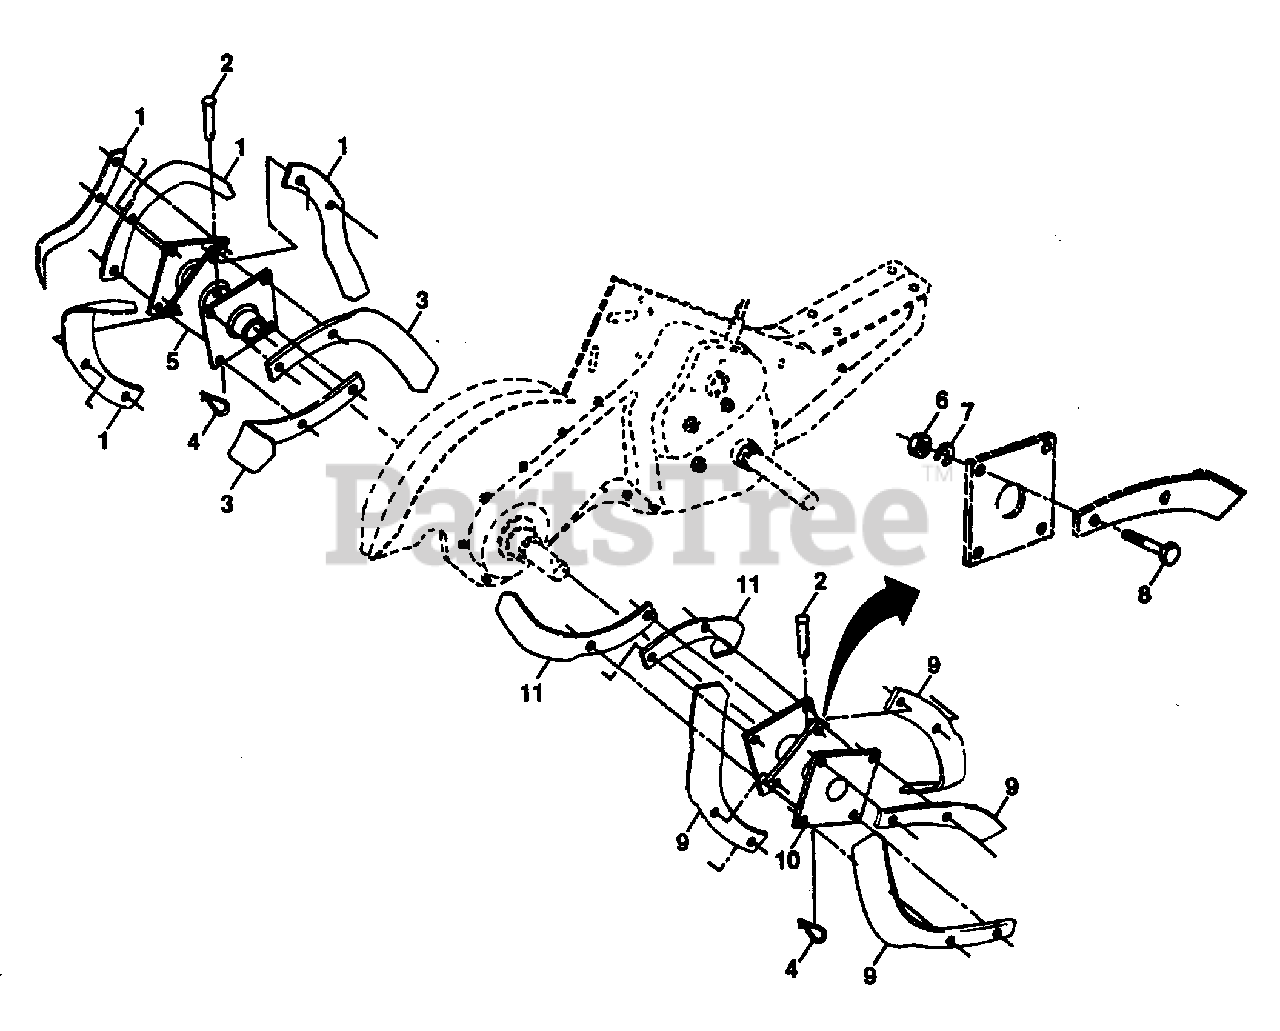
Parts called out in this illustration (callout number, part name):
1	Tine, Outer, L.H. (AYP part number)
2	Pin, Shear (AYP part number)
3	Tine, Inner, L.H. (AYP part number)
4	Clip, Hairpin (AYP part number)
5	Assembly, Hub and Plate, L.H. (AYP part number)
6	Nut, Hex 3/8-24 (AYP part number)
7	Washer, Lock 3/8 (AYP part number)
8	Bolt, Hex 3/8-24 x 1 (AYP part number)
9	Tine, Outer, R.H. (AYP part number)
10	Assembly, Hub and Plate, R.H. (AYP part number)
11	Tine, Inner, R.H. (AYP part number)
